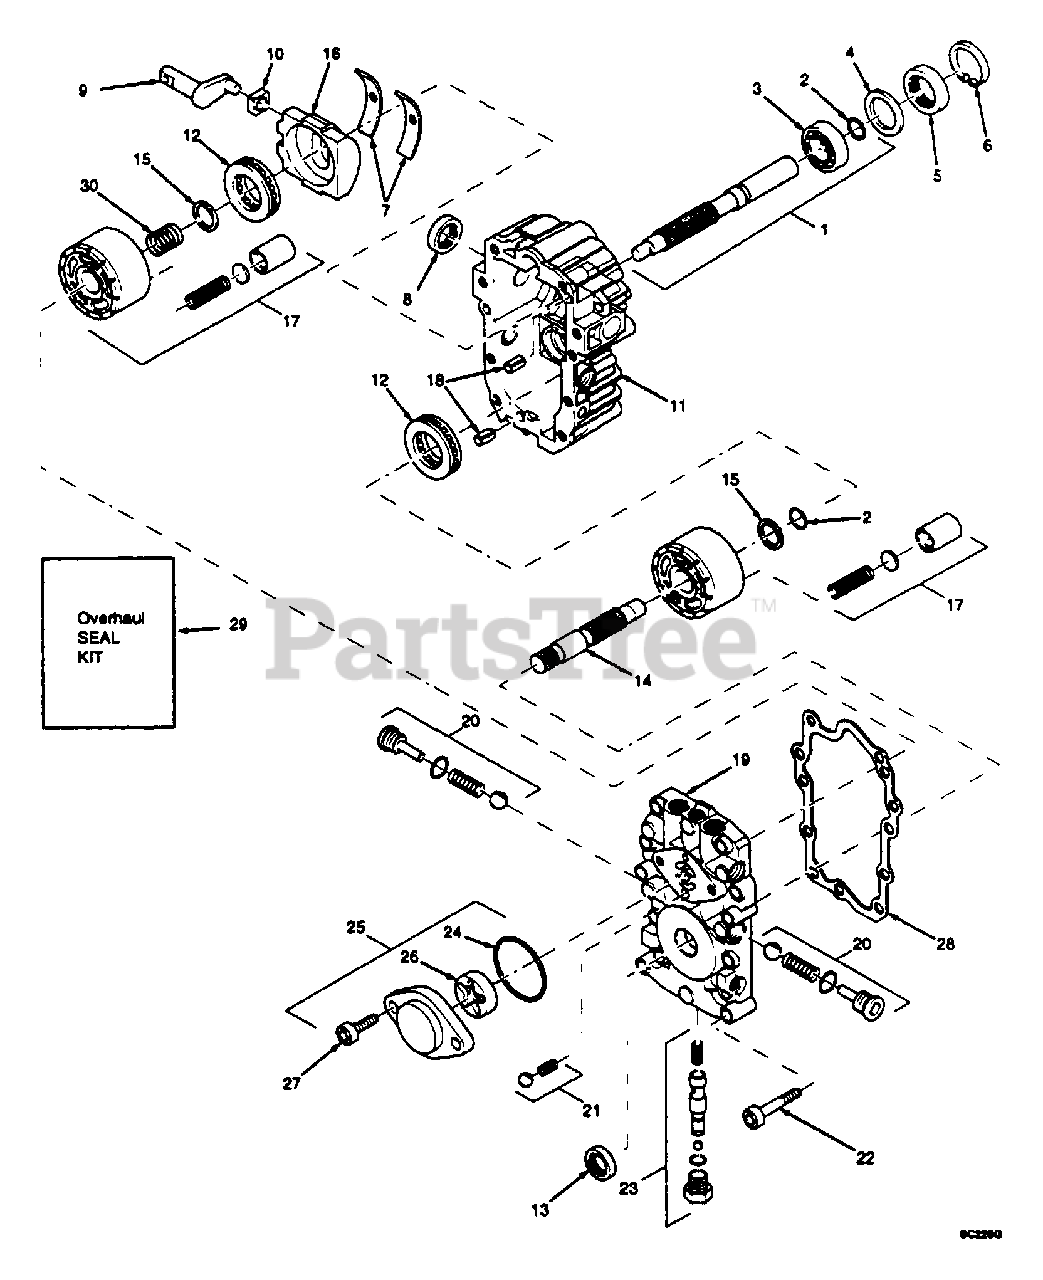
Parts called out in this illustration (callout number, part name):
1	Pump Shaft Kit
2	Wire Retaining Ring
3	Ball Bearing
5	Lip Seal (16 x 35 x 7)
6	Retaining Ring
7	Cradle Bearing
8	Lip Seal (12 x 35 x 7)
9	Trunnion Arm
10	Slot Guide
11	Transmission Housing Kit RH
11	Transmission Housing Kit LH
12	Thrust Ball Bearing Assembly
13	Lip Seal (15 x 24 x 7)
14	Motor Shaft
15	Block Thrust Washer
16	Variable Swash Plate
17	BDP-10L Block Assembly
18	Pin ST Holder
19	Center Section Kit
20	Check Valve Kit
21	Charge Relief Kit
22	Socket Head Cap Screw
23	Bypass Valve Kit
25	Charge Pump Cover
26	Gerotor Assembly
27	Capscrew (6mm x 20")
28	Center Section Gasket
29	Overhaul Seal Kit
30	Spring Block
